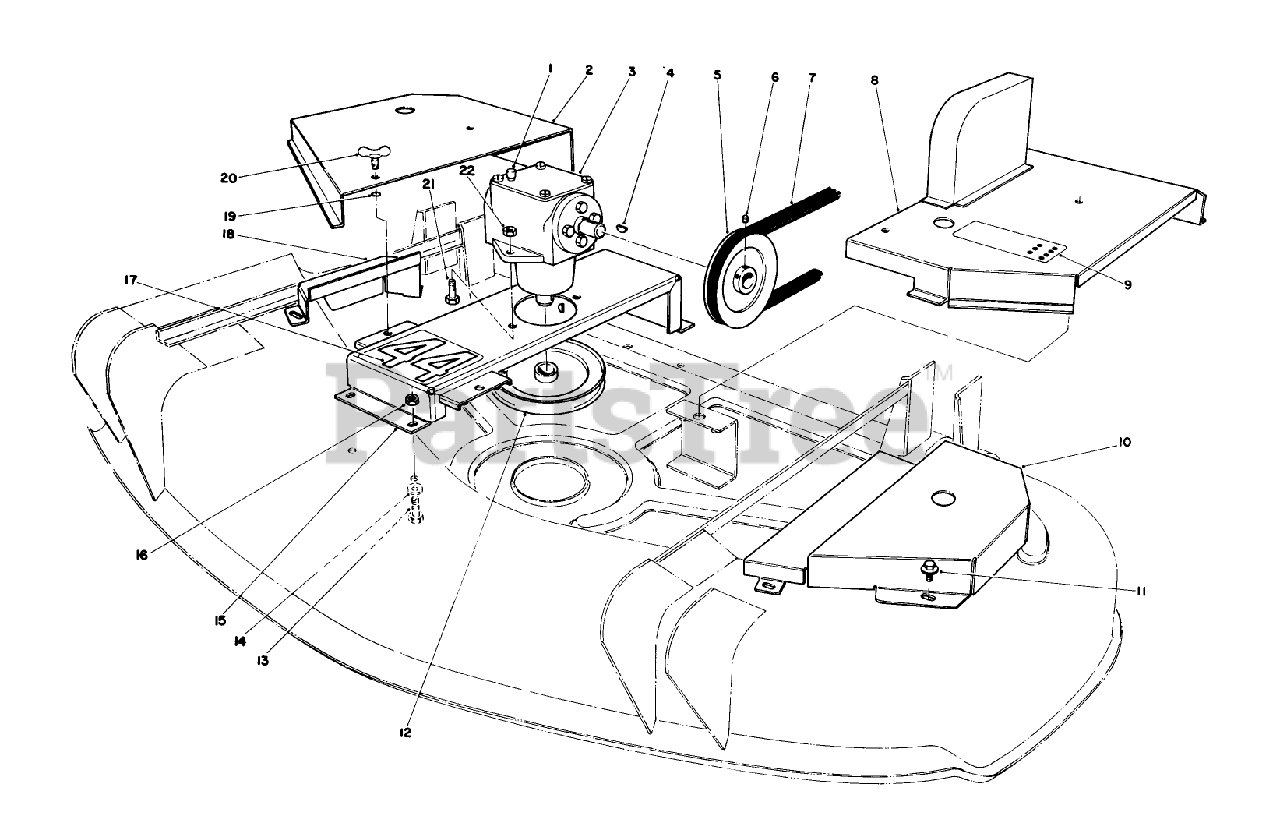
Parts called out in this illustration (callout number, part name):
2	Cover-Deck
3	GEARBOX-DRIVE, DECK
4	KEY-WOODRUFF
5	Pulley-Input (Incl. Ref. #6)
6	SCREW-SET, SQH
7	V-BELT-DRIVE, DECK
8	Cover-Deck
9	DECAL
10	Cover-LH
11	SCREW-HHFTF
12	Pulley-Output (Incl. Ref. #6)
13	SCREW-HH
14	WASHER-PLAIN
15	Bracket-Gearbox
16	NUT-LOCK, CONE
17	DECAL-44 INCH
18	Cover-RH
19	RING-SNAP
20	STUD-HEAD, WING
21	SCREW-HH
22	NUT-LOCK, CONE
